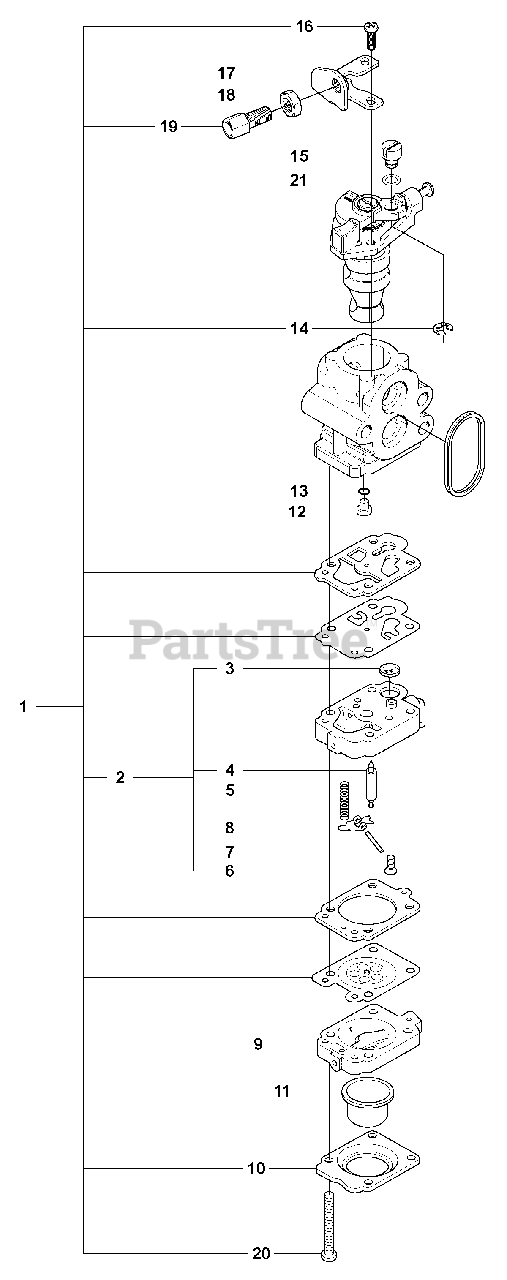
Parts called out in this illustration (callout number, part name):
1	CARBURETOR A
2	CARBURETOR BODY
3	CARBURETOR BODY
4	CARBURETOR BODY
5	CARBURETOR BODY
6	CARBURETOR BODY
7	CARBURETOR BODY
8	CARBURETOR BODY
9	BODY
10	COVER
11	PUMP
13	O-RING
15	SWIVEL
16	SCREW
17	RP_BRACKET
18	NUT
19	SCREW
20	SCREW
21	WASHER
